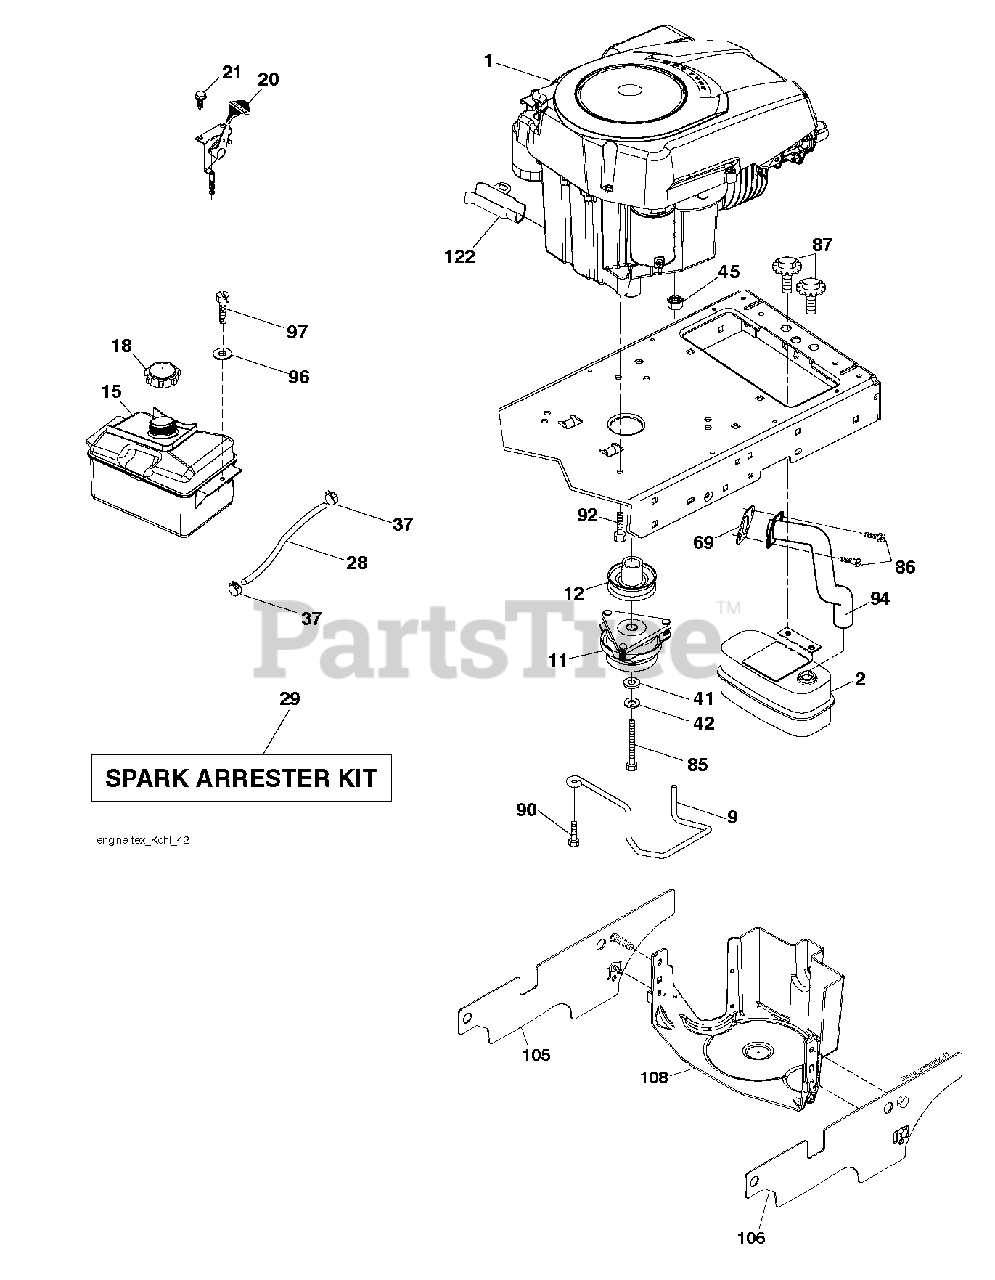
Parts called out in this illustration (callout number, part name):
2	MUFFLER.SINGLE.CYL.KOHL/B&S
9	KEEPER.BELT.ENGINE.4.2
11	RB.CLUTCH.OGURA.4.4.PD
12	PULLEY.ENGINE.TUFFTORQ
15	RP TANK FUEL FRT 1.5 GAL
18	CAP ASM.FUEL.2.25"FR.
20	CONTROL.TH/CK.C.
21	SCREW.#10 X 0.750.BOS
28	LINE.FUEL.20
29	KIT.SPARK ARRESTOR 794945 B&S
37	HOSE CLAMP
42	LOCKWASHER
45	NUT
69	GASKET.EXHAUST.KOHLER
85	BOLT HEX 7/16-20X4-1/4"
86	SCREW.SOCKET HD.5/16-1
87	BOLT, 5/16-18 X 1 3/4
90	SCREW 3/8-16X1
92	SCREW 3/8-16X1
94	RP.TUBE.EXHAUST.KOHL.COURAGE
97	SCREW HEXWSHR 1/4-20X3/4
108	ENGINE COVER
122	EXTENSION DRAIN OIL
